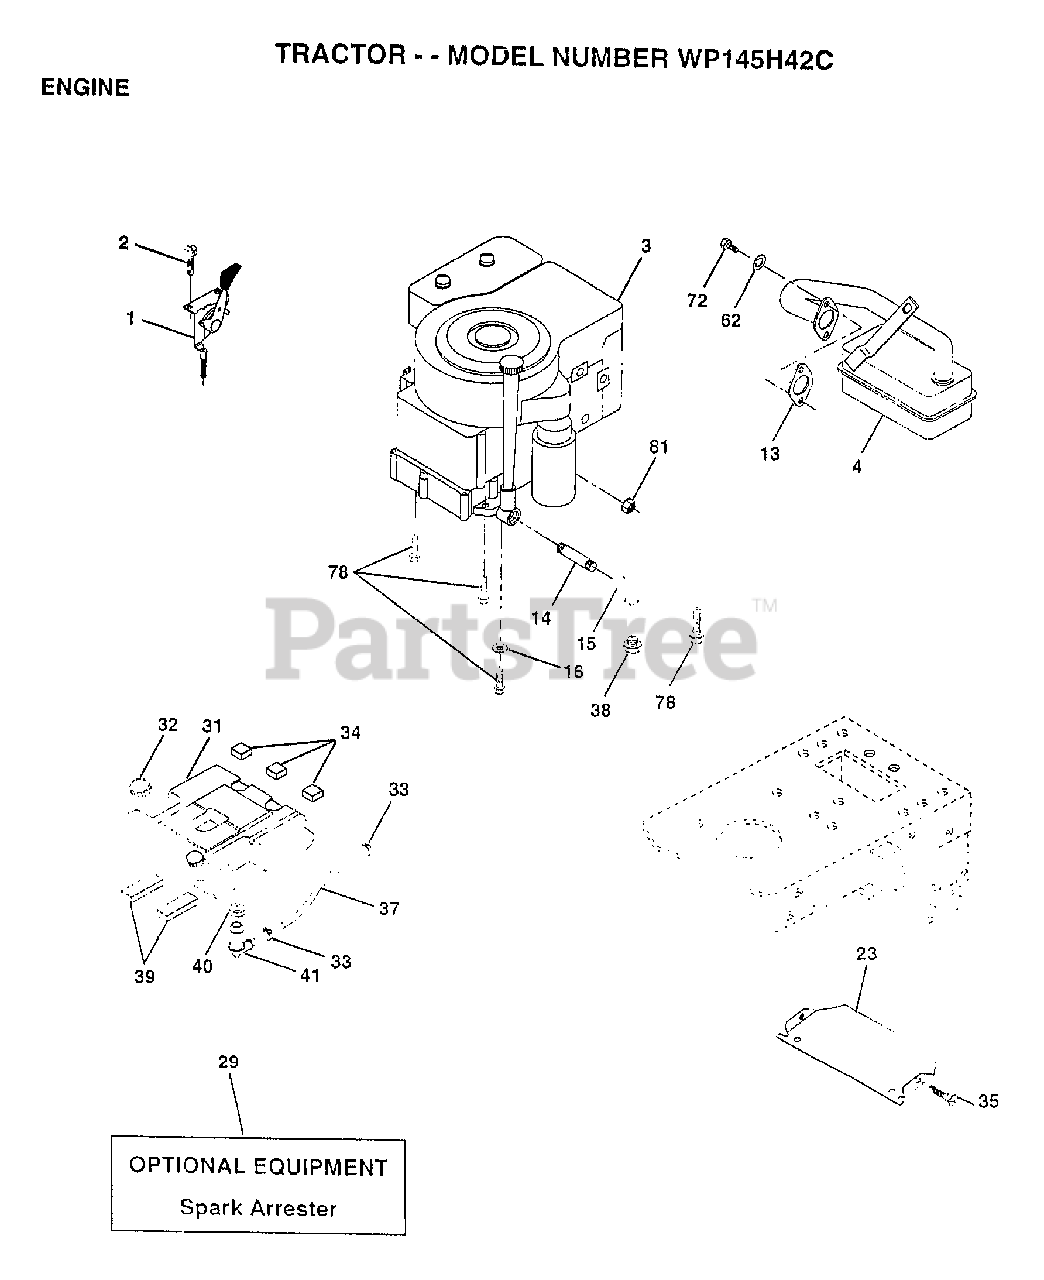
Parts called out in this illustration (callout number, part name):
1	"CONTROL,THROTTLE"
2	SCREW LT
4	MUFFLER
13	GASKET ENG 1 313 LD TIN PLATED
14	PIPE NIPPLE
15	ELBOW
16	LOCKWASHER
23	SHIELD-HEAT
31	TANK FUEL REAR
32	CAP ASM FUEL
33	HOSE CLAMP
34	PAD-SPACER LT
35	SCREW
37	FUEL LINE T
39	PAD IDLER TI
40	BUSHING OUTLET T
41	STEM.TANK.FUEL
62	LOCKWASHER
72	SCREW
78	SCREW
81	NUT
